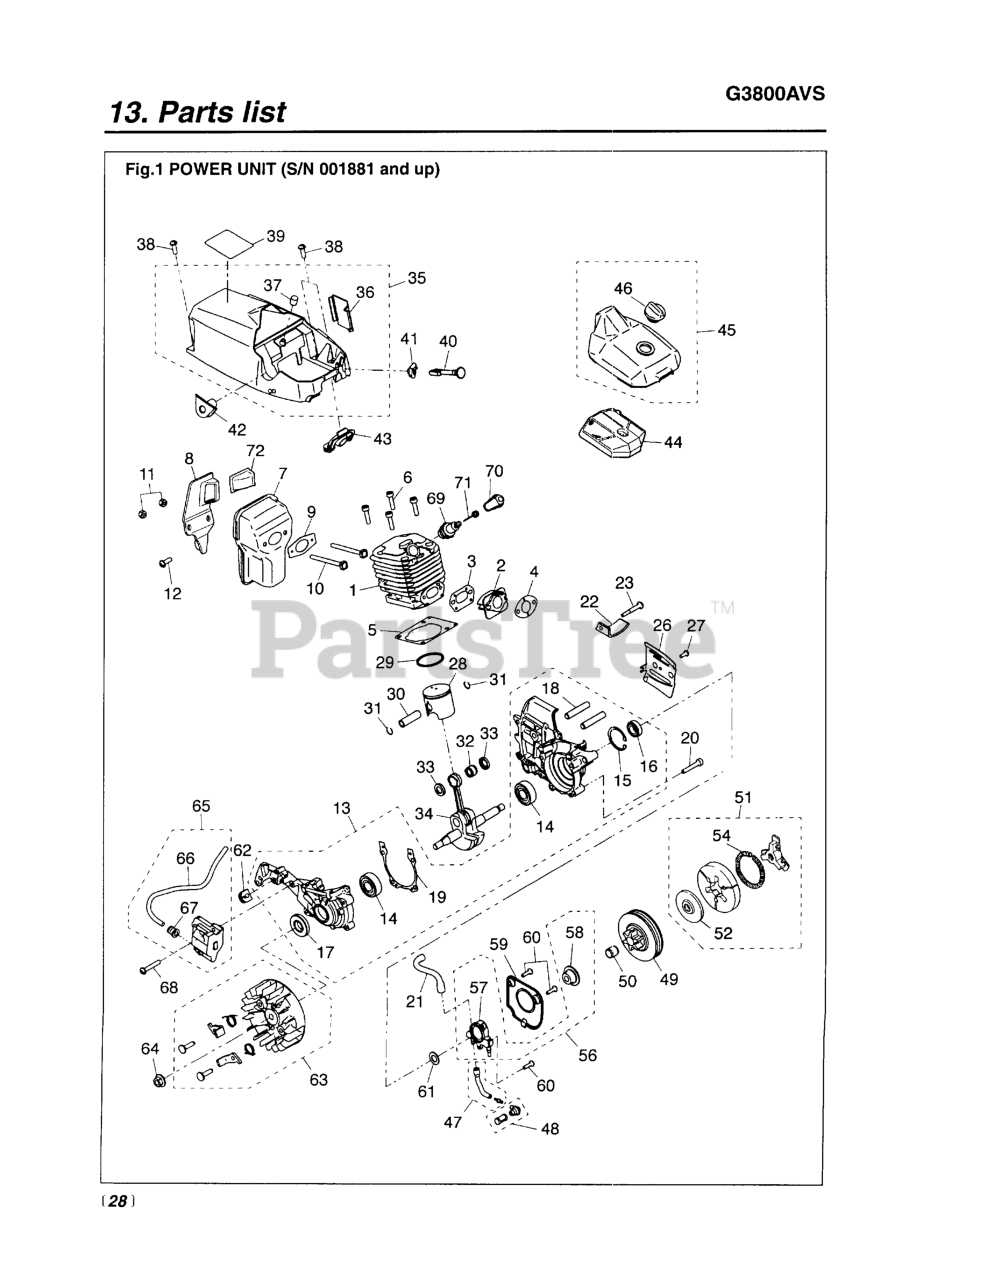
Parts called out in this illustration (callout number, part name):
1	CYLINDER
2	INSULATOR
3	GASKET, INLET (RPLS-14122)
4	GASKET
5	GASKET, CYLINDER
7	MUFFLER
8	STAY
9	GASKET, MUFFLER
10	BOLT, MUFFLER
11	NUT, MUFFLER (RPLS 3356-15230
12	SCREW (REPLACES 2616-24320)
13	CRANKCASE ASSEMBLY
15	RING, SNAP, M32 x 1.2
16	SEAL, OIL (RPLS 1100-21210)
17	SEAL, OIL
18	STUD (RPLS 0205-50825)
19	GASKET, CASE
20	BOLT
21	PIPE
22	CATCHER, CHAIN (RPLS -25210)
26	PLATE (A)
28	PISTON
29	RING, PISTON
30	PIN, PISTON
31	RING, SNAP
32	BEARING
33	WASHER
34	SHAFT COMPLETE
35	COVER COMPLETE
39	LABEL
40	ROD, CHOKE
41	GROMMET, CHOKE
42	GROMMET
43	GROMMET, THROTTLE
44	CLEANER, AIR COMP
45	COVER, CLEANER COMP
46	KNOB (RPLS 3356-83322)
47	PIPE
48	FILTER COMPLETE
49	DRUM, CLUTCH
50	BEARING
52	PLATE
54	SPRING
57	PUMP, OIL (USE 848-C40-67A1)
58	WORM GEAR
59	COVER, PUMP
60	SCREW
61	WASHER
62	GROMMET
63	ROTOR COMPLETE
65	COIL COMPLETE
66	CORD
67	CAP
68	SCREW
70	CAP
71	SPRING PLUG (RPLS 3310-71320)
72	ARRESTER, SPARK
